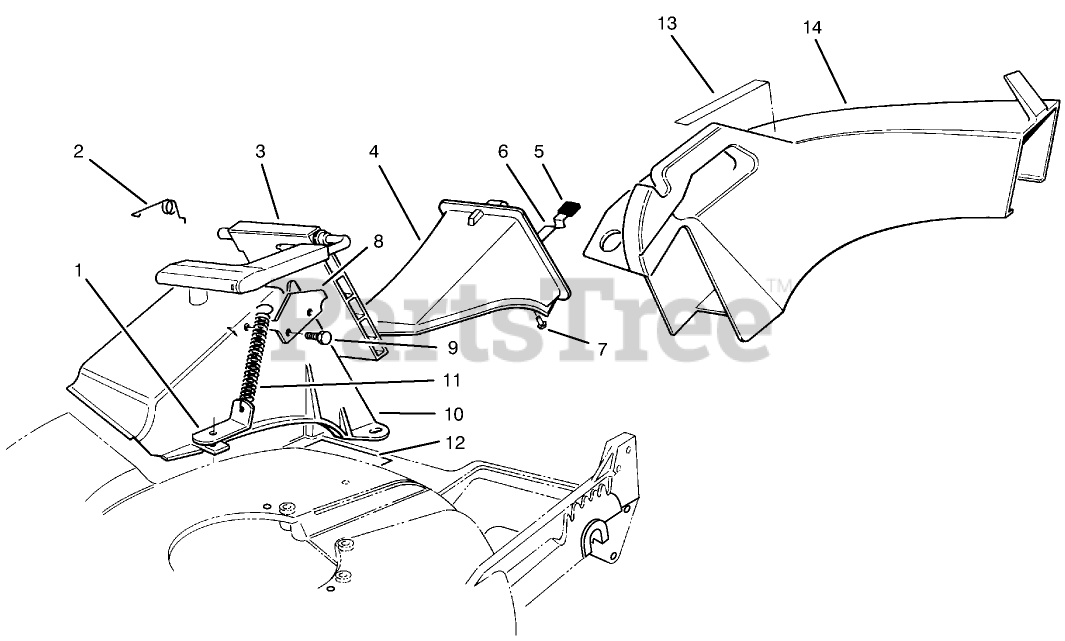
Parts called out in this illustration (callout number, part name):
1	BRACKET-SPRING
2	RETAINER-DOOR
3	DISCHARGE DOOR ASM
4	Plug Assembly (Incl. Ref. #5-7)
5	GRIP-LATCH
6	LATCH-PLUG, DISCHARGE
7	RIVET-HEAD, FLAT
8	LATCH-PLATE
9	SCREW-PLASTITE
10	TUNNEL-DISCHARGE
11	SPRING-DOOR
12	DECAL - CAUTION
13	DECAL - CAUTION
14	Chute-Discharge (Incl. Ref. #13)
